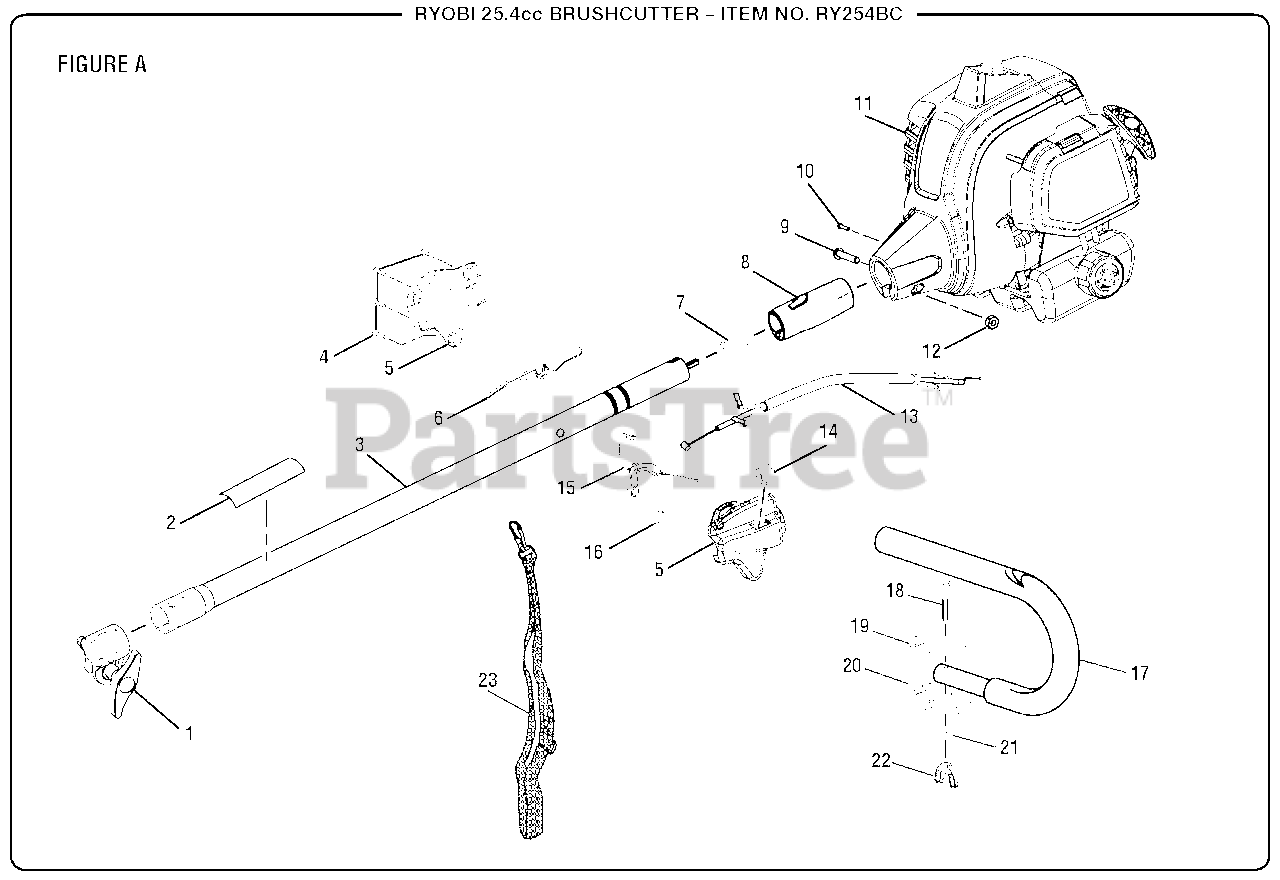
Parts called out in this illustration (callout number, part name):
1	Boom Clamp Assembly
2	Warning Icon Label
3	Upper Boom Assembly
4	Screw (M4 x 20 mm, T20 Torx Hd ST)
5	Control Handle Assembly
6	Trigger Lock
7	Compression Spring
8	Rear Handle Grip
9	Screw (M6 x 30 mm, T27 Torx Button Hd)
10	Screw (M4 x 8 mm, T20 Torx Pan Hd ST)
11	Powerhead Assembly w/Labels
12	Hex Nut (M6 x 1)
13	Throttle Cable and Wire Assembly
14	On/Stop Switch
15	Trigger
16	Trigger Spring
17	"J" Handle and Grip
18	Bolt (1/4-20 x 1-1/2 in, Hex Hd)
19	Top "J" Handle Clamp
20	Bottom "J" Handle Clamp
21	Washer (ID725 x OD16 x 15t)
22	Wing Nut (1/4-20)
23	Shoulder Harness
